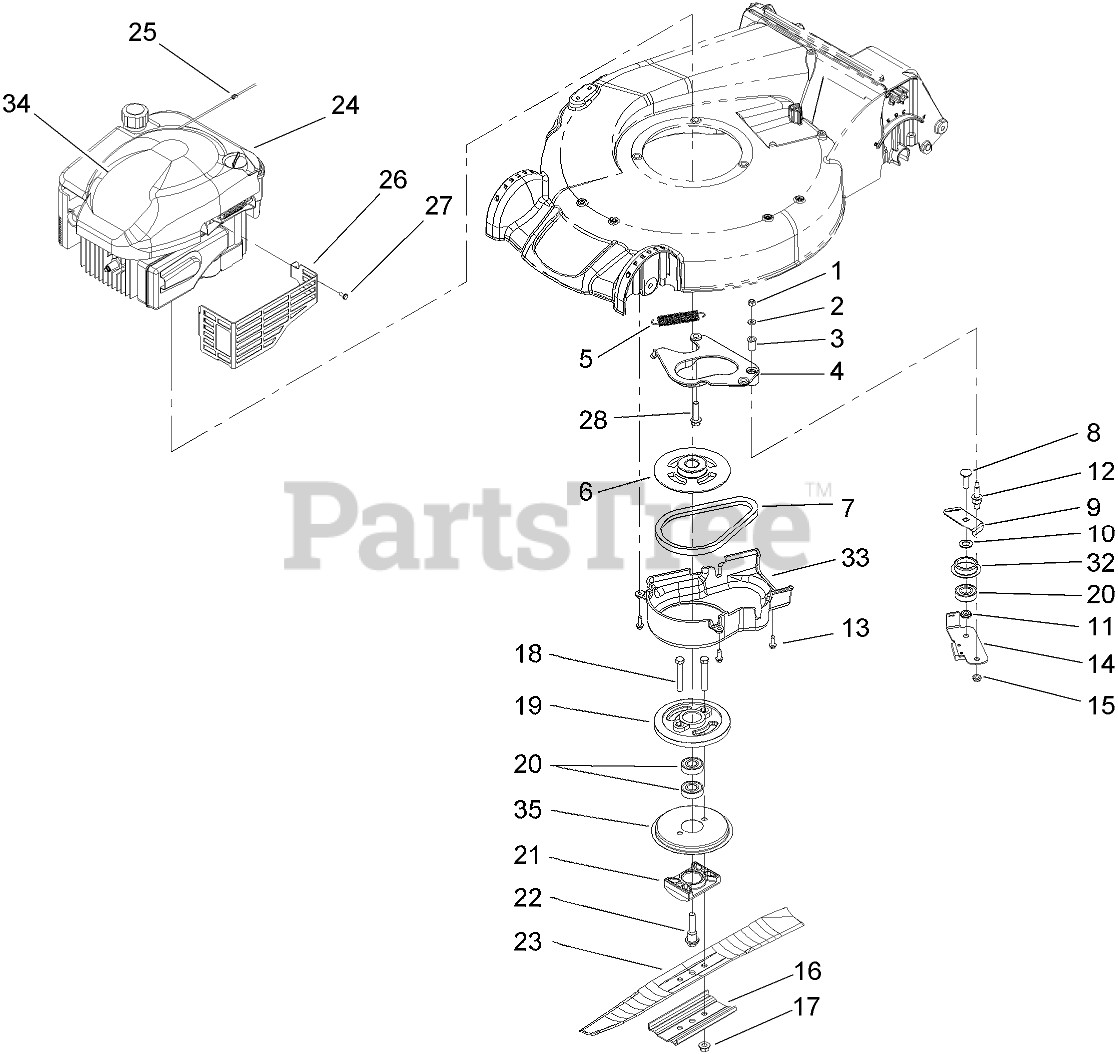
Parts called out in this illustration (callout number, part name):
1	NUT-LOCK, NI
2	WASHER-FLAT
3	BUSHING
4	PLATE-ANCHOR
5	SPRING-TENSION, BRAKE
6	PULLEY
8	BOLT-CARR
9	PLATE-GUIDE
10	WASHER-PLAIN
11	SPACER-BEARING
12	BOLT-SHOULDER
13	SCREW-HWHTF
14	BRAKE ARM ASM
16	SUPPORT-BLADE
17	NUT-LOCK
18	SCREW-HH
19	DRUM
20	BEARING-BALL
21	SUPPORT-BLADE
22	BOLT-CRANK
23	BLADE-BAGGING
25	STOP-ROPE
26	SHIELD-MUFFLER
27	SCREW-TAPTITE
28	SCREW-HWH
32	RETAINER-BELT
34	DECAL-RECOIL
35	DISC
